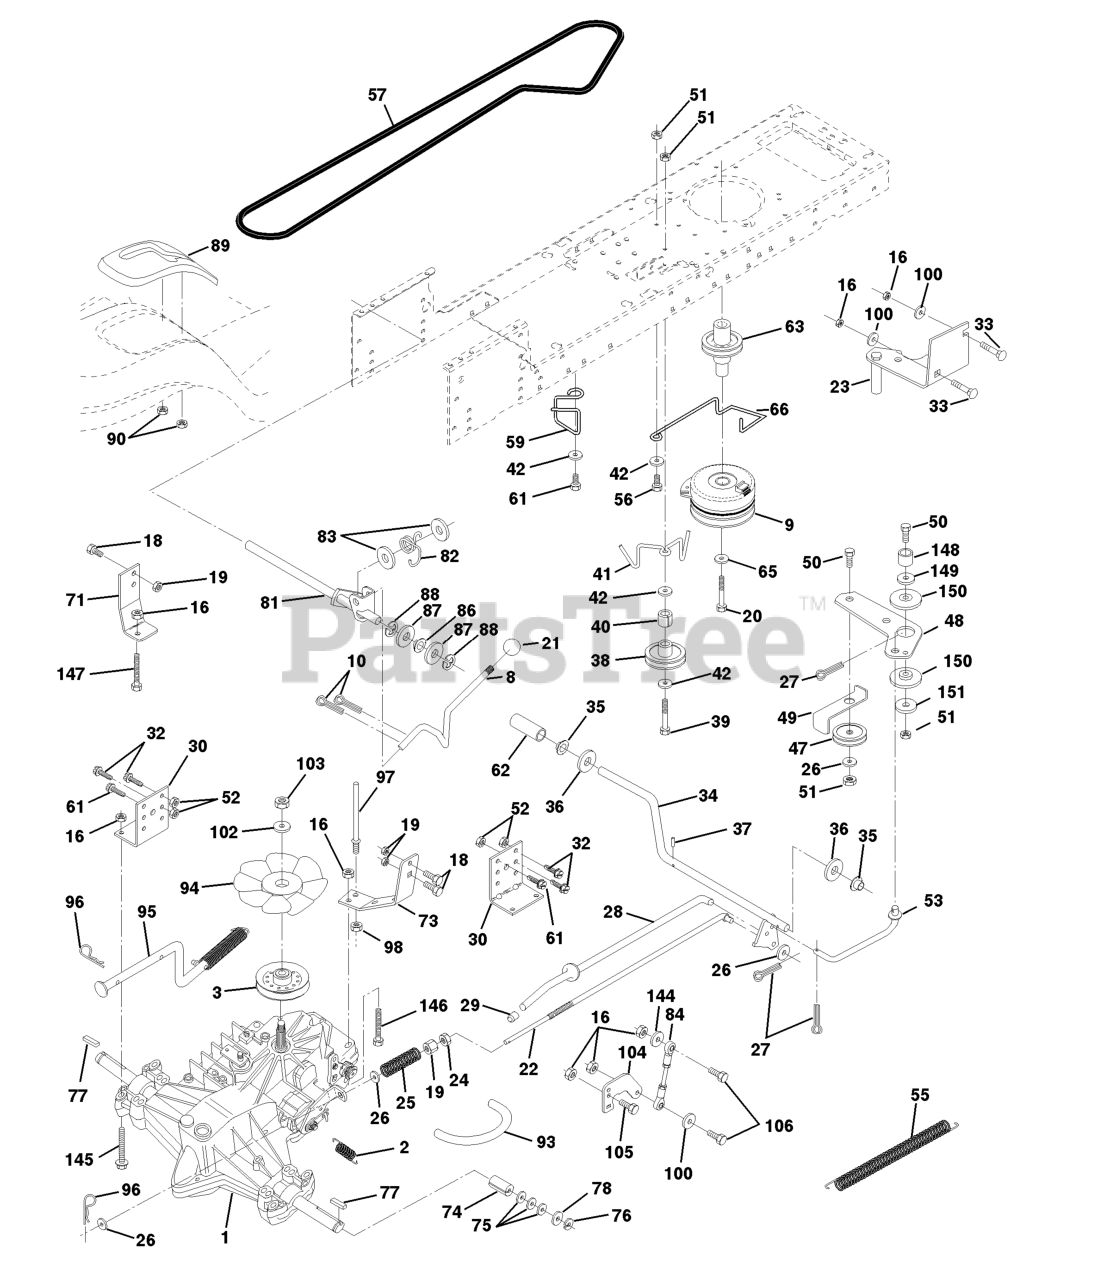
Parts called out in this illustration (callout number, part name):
1	TRANSAXLE ASSEMBLY
2	SPRING BRAKE
3	PULLEY, TRANSAXLE
8	ROD SHIFT FENDER
9	CLUTCH.ELECT.EVX.
10	PIN COTTER
16	NUT.71038.31-18.HEX.NYLOCK
18	BOLT
19	NUT
20	BOLT HEX
21	KNOB.DELUXE.(PISTOL.GRIP).BLAC
22	ROD BRAKE HYDRO
23	BRACKET, ASM CLUTCH MTG
24	NUT
25	SPRING ROD LT
26	WASHER
27	COTTER PIN
28	ROD BRAKE PARK LT
29	PLUNGER CAP
30	BRACKET TRANSAXLE
32	BOLT
33	RP BOLT 5/16-18 X3/4 ZN/YEL GR
34	SHAFT, FOOT PEDAL
35	BEARING.NYLON
36	WASHER LT
37	DRIVE PIN
38	FLAT IDLER PULLEY
41	KEEPER.BELT.IDLER.FLAT
42	WASHER
47	IDLER PULLEY
48	BELLCRANK, CLUTCH
49	RETAIN BELT
50	BOLT
52	LOCKNUT
53	LINK, CLUTCH LT
55	SPRING, RETURN LT
57	DRIVE BELT, LTH & YTH TRACTORS
59	KEEPER CENTER SPAN
61	SCREW
62	COVER, PEDAL (1 2)
63	PULLEY, CLUTCH ELECT EVX
65	LOCKWASHER
66	KEEPER BELT ENGINE
71	STRAP LH TORQUE
73	STRAP TORQUE RH HYDRO
74	SPACER SPLIT
77	SQUARE KEY
81	SHAFT ASSY
82	SPRING,TORSION
83	WASHER
89	SHIFT CONSOLE
90	NUT.PUSH.3/16
93	LINE FUEL HYD 4"
94	FAN 7" HYDRO
95	CONTROL ARM, BYPASS HYDRO
96	RETAINER M
97	KEEPER BELT RH
100	WASHER M
103	NUT.HEX.1/2-20
104	CONTROL ARM
106	BOLT.5/16-18X1-1/4 FULL.THREAD
144	Washer 11/32 x 5/8 x 16 Ga.
145	BOLT
146	Bolt Hex Flghd 5/16-18 x 2-1/4
147	Bolt Hex Flghd 5/16-18 x 1-1/2
149	SPACER RETAINER
150	BUSHING NYLON COLLERED
151	WASHER 12/32X2X10GA
